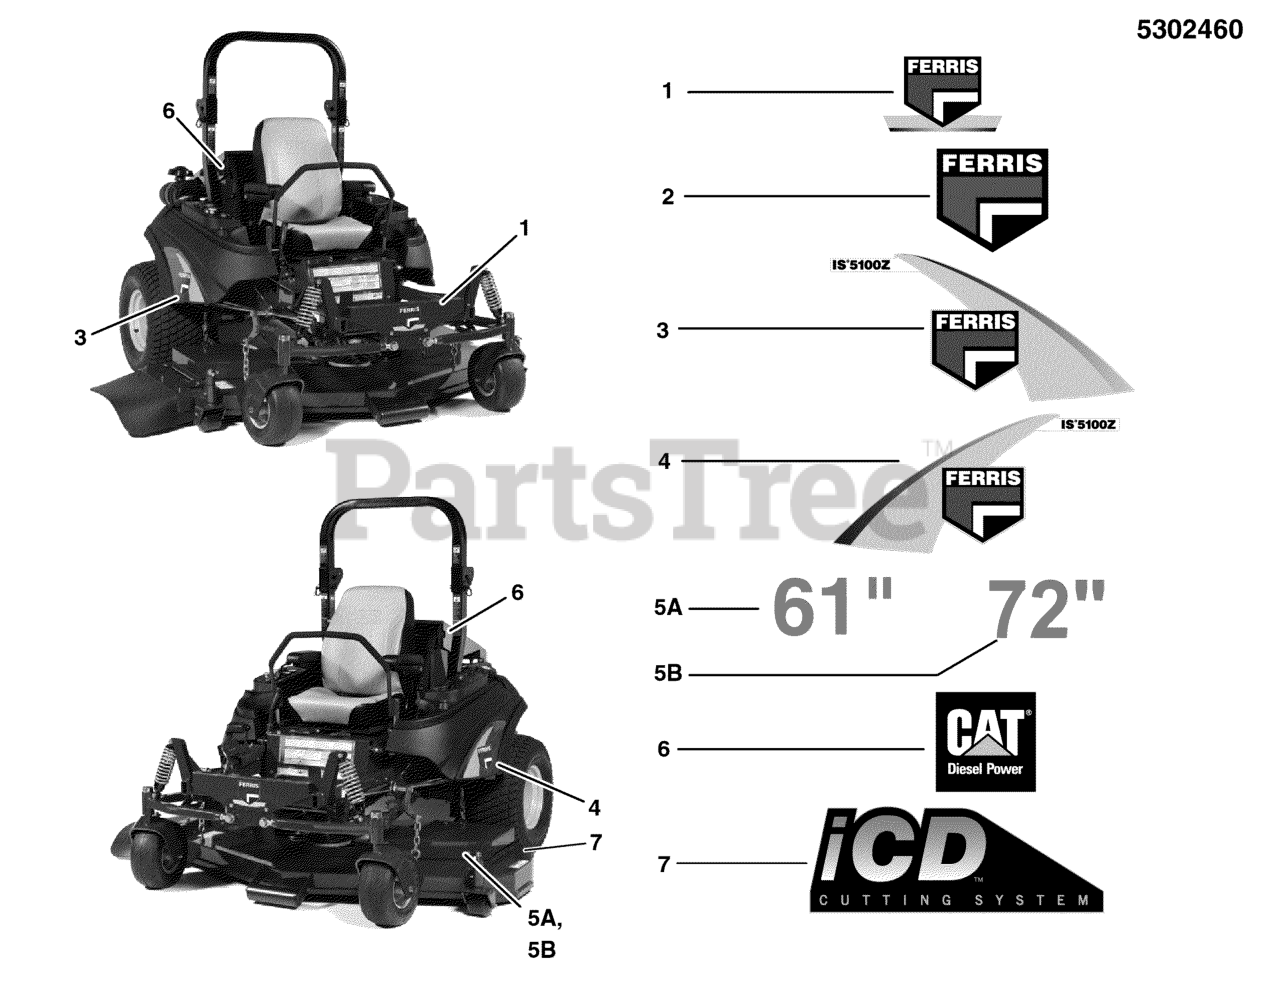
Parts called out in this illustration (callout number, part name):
2	DECAL, FERRIS LOGO, 9-3/8
3	DECAL, BADGE, IS5100, RH
4	DECAL, BADGE, IS5100, LH
5A	DECAL, 61"
5B	DECAL, 72"
6	DECAL, CAT DIESEL POWER
7	DECAL, ICD CUTTING SYSTEM
